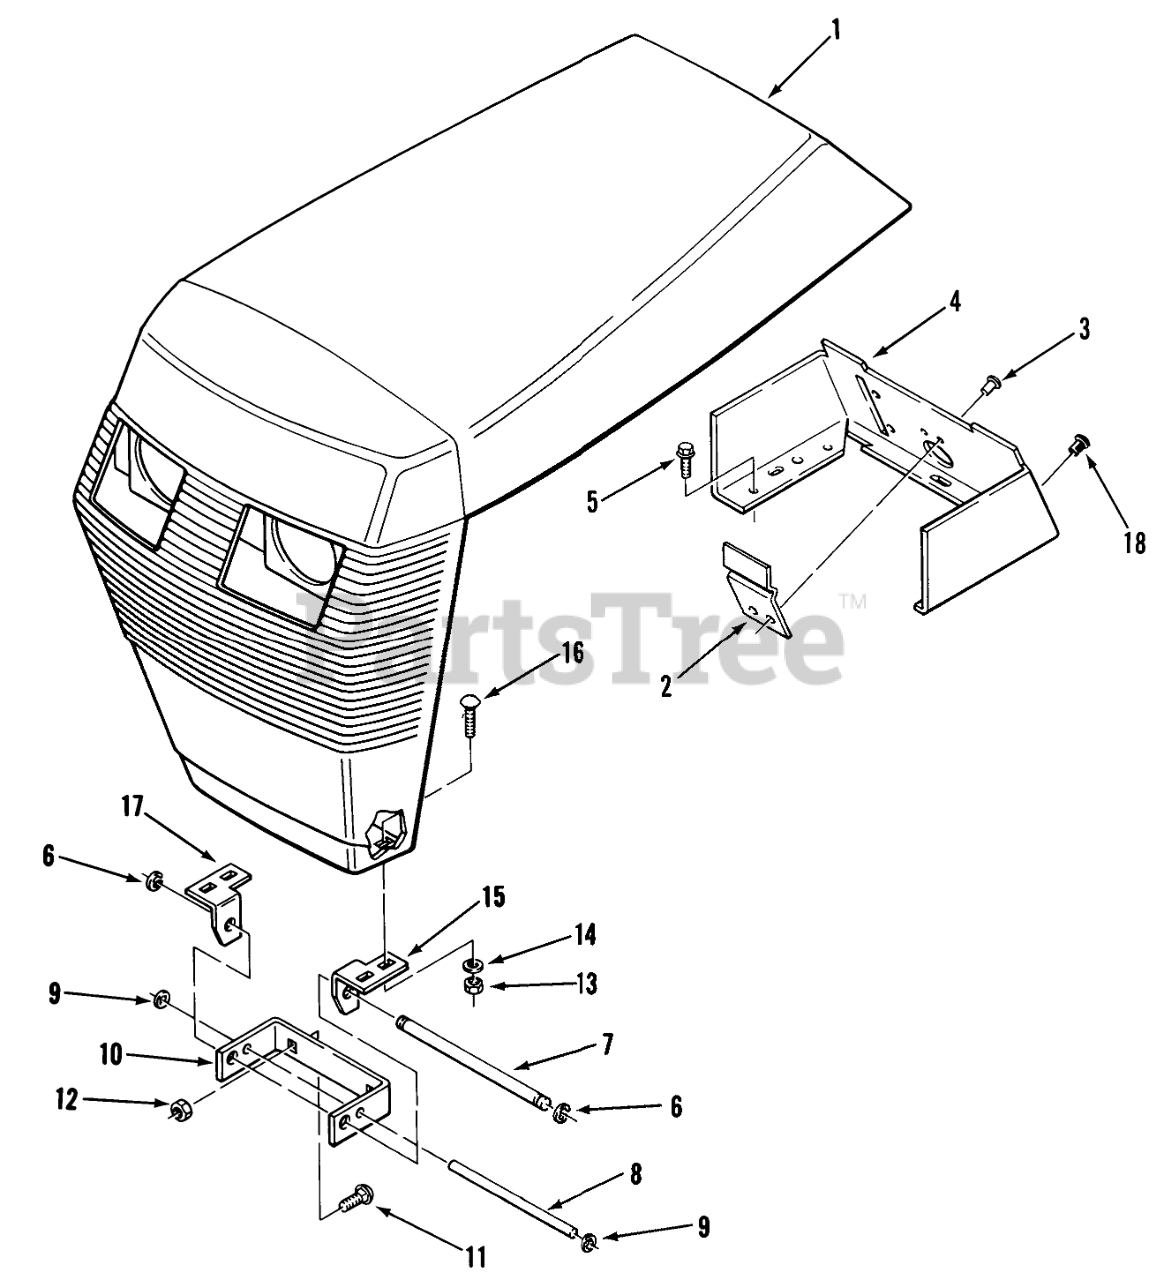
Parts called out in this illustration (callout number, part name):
1	Hood LT-832, LT-1032, LT-1137 Only
1	Hood LT-1637, LT-1642 Only
2	Hood Latch
3	RIVET
4	Console
5	SCREW
6	RING-RETAINING
7	ROD-GRILL PIVOT
8	ROD-HOOD STOP
9	SPEED NUT
10	Bracket Hood Pivot
11	Bolt-Carriage
12	Nut
13	Nut
15	BRKT-GRILL PIVOT R (NS)
16	Bolt-Carriage
17	BRKT-GRILL PIVOT R
18	NYLON PLUG
